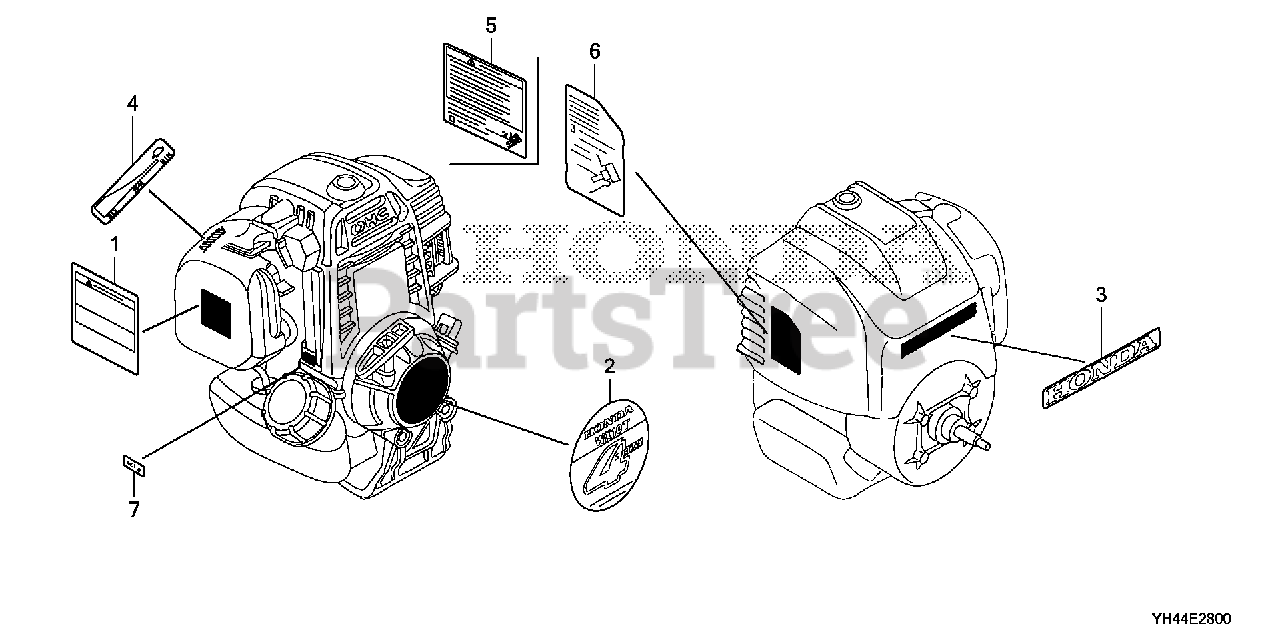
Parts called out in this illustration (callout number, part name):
1	MARK, OPERATOR CAUTION (ENGLISH)
3	MARK, HONDA
4	MARK, THROTTLE INDICATION
5	LABEL, SPARK WARNING
7	MARK, TYPE (AD5)
